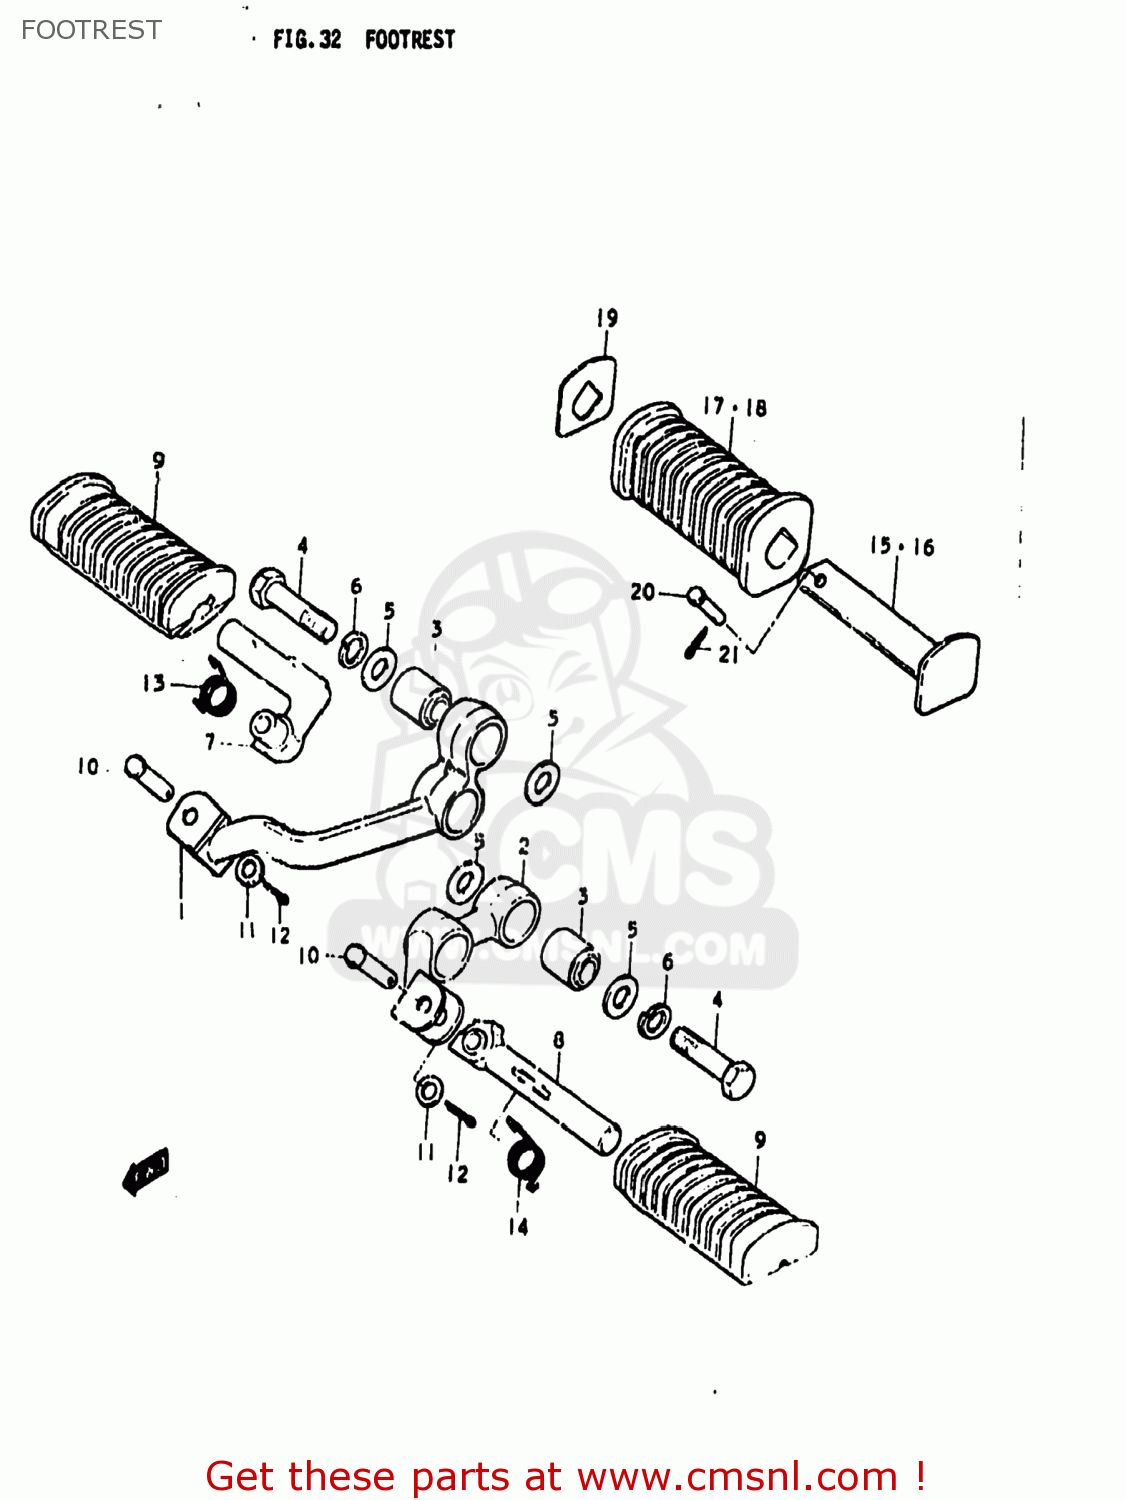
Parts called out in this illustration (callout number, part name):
1	BAR,FRONT FOOTREST
2	BAR,FRONT FOOTREST,LEFT
3	BUSH
4	BOLT
5	WASHER (10.1X21X2.3)
6	LOCK WASHER
7	BAR,FRONT FOOTREST,RIGHT NO
8	BAR,FRONT FOOTREST,LEFT NO
9	RUBBER,FR FOOTREST
10	PIN
11	WASHER
12	PIN 20X20
13	SPRING
14	SPRING
15	BAR,REAR FOOTREST
16	BAR,REAR FOOTREST
17	RUBBER,PILLION FOOTREST
18	RUBBER, LH
19	WASHER,REAR FOOTREST RUBBER
20	PIN
21	PIN
